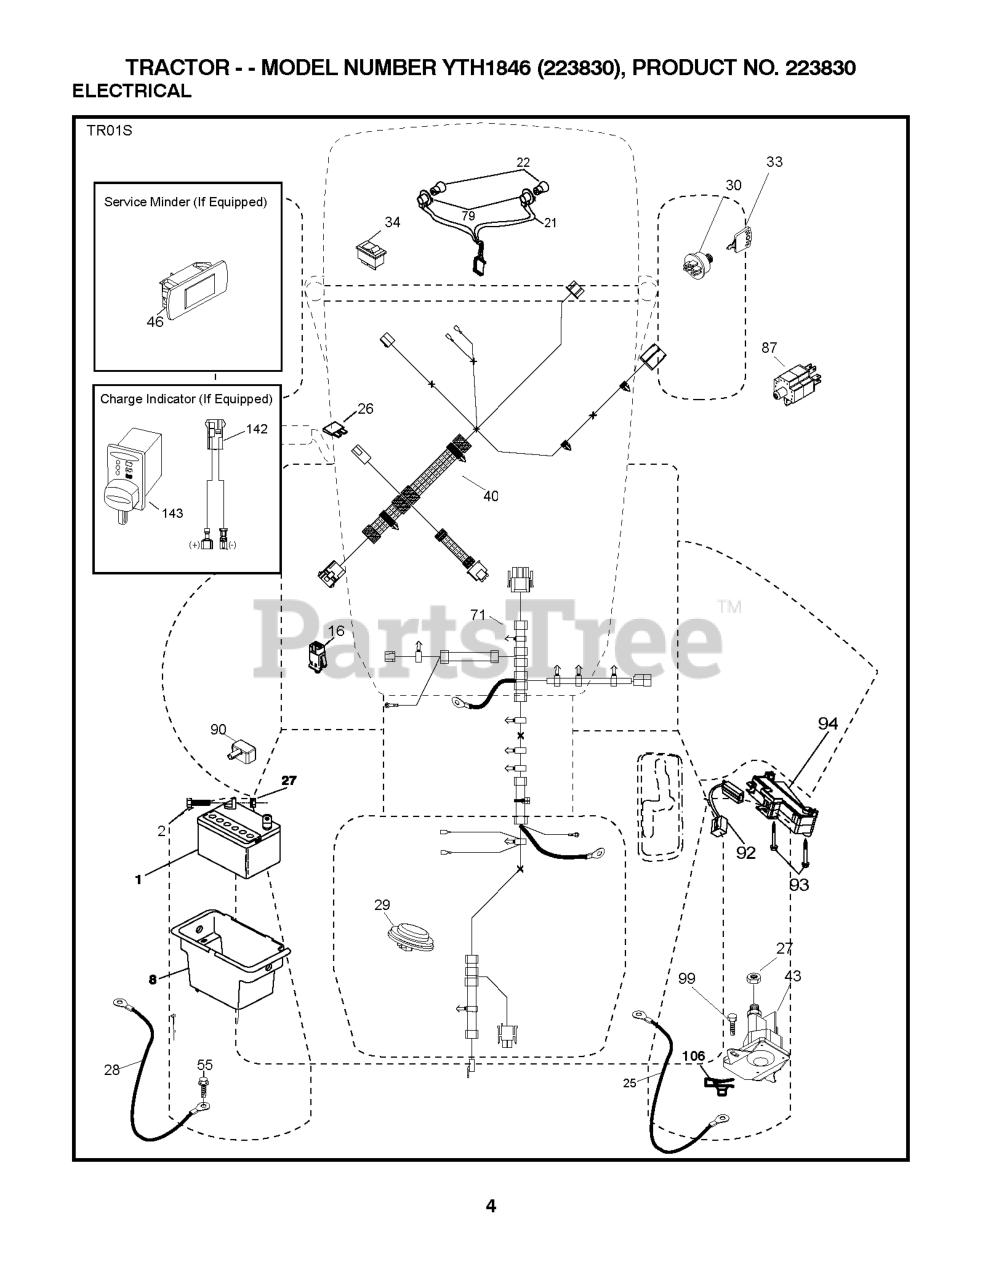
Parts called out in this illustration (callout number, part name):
1	Battery 12 Volt 25 Amp
2	BOLT.HEX.1/4.X.3/4.DICHROMATE
8	BOX.BATTERY.MNT.REAR.L
16	SWITCH INTERLOOK PUSH-IN
21	HARNESS.LIGHT W/4152J BULBS
25	CABLE.BATT.RED.8GA.17
26	FUSE 20AMP
28	CABLE.GROUND.REAR.BATTERY.8G
29	SWITCH.SEAT.DELTA.OPC.
30	SWITCH.IGN.DELTA.W.LGH.ROS
33	KEY.CHAIN.BLISTER.PACK.GEN.USA
40	HARNESS.TEX.DASH.MAN.REAR BATT
55	SCREW 5/16"
71	HARNESS.CHASSIS.RRBATT.RDYSTRT
79	BULB HOLDER ASM.
87	SWITCH.INTRLCK.CLUTCH.
90	COVER.TERMINAL.BATTERY
92	HARNESS.PIGTAIL.CONSLE
94	MODULE.REVERSE.ROS
99	SCREW HEXWSHR 1/4-20X3/4
106	1/4-20 U NUT
